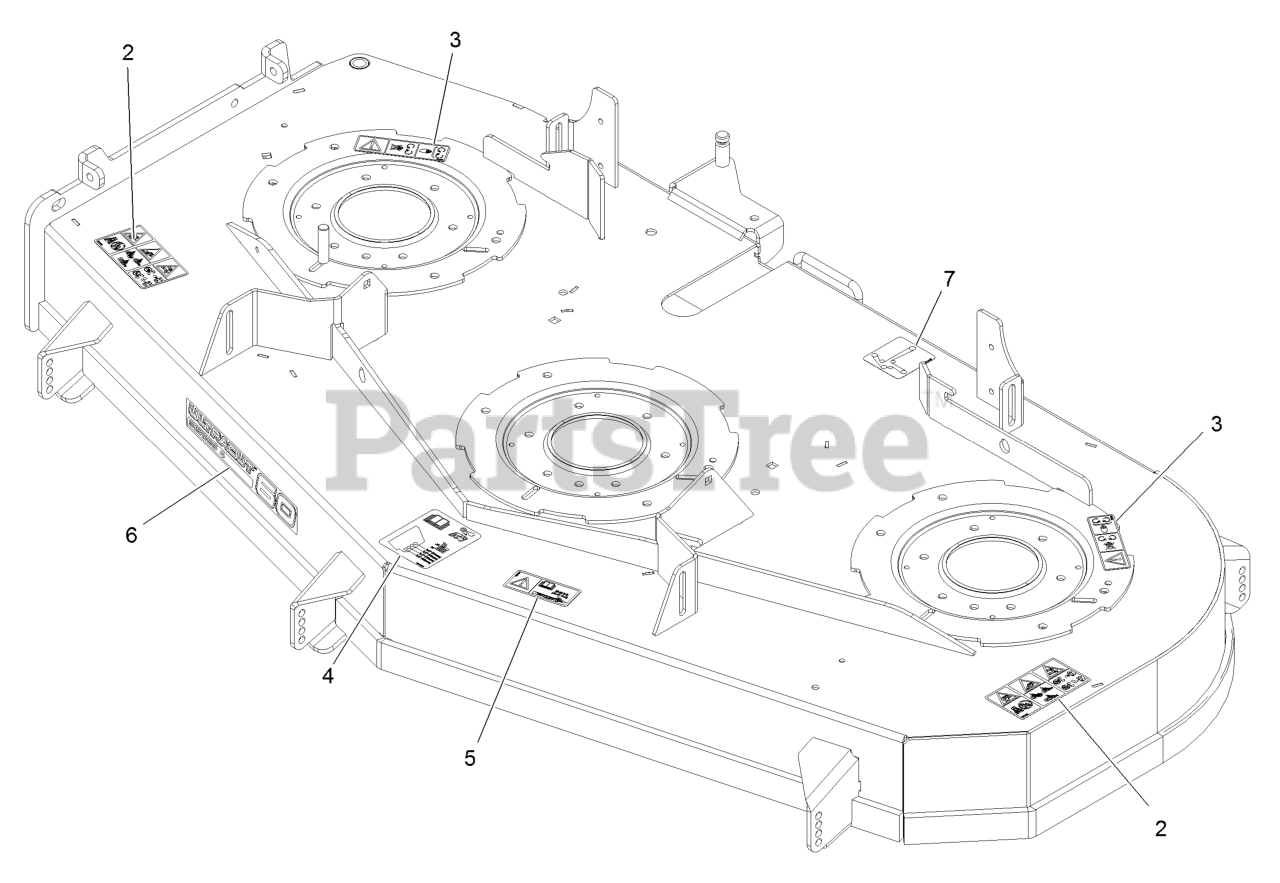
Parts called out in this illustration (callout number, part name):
2	DECAL-DANGER THROWN OBJECTS
3	DECAL-COVER, MISSING
4	DECAL-ROLLER, ANTI-SCALP
5	DECAL-BOLT TORQUE
6	DECAL, 604
7	DECAL-ROUTING, BELT
